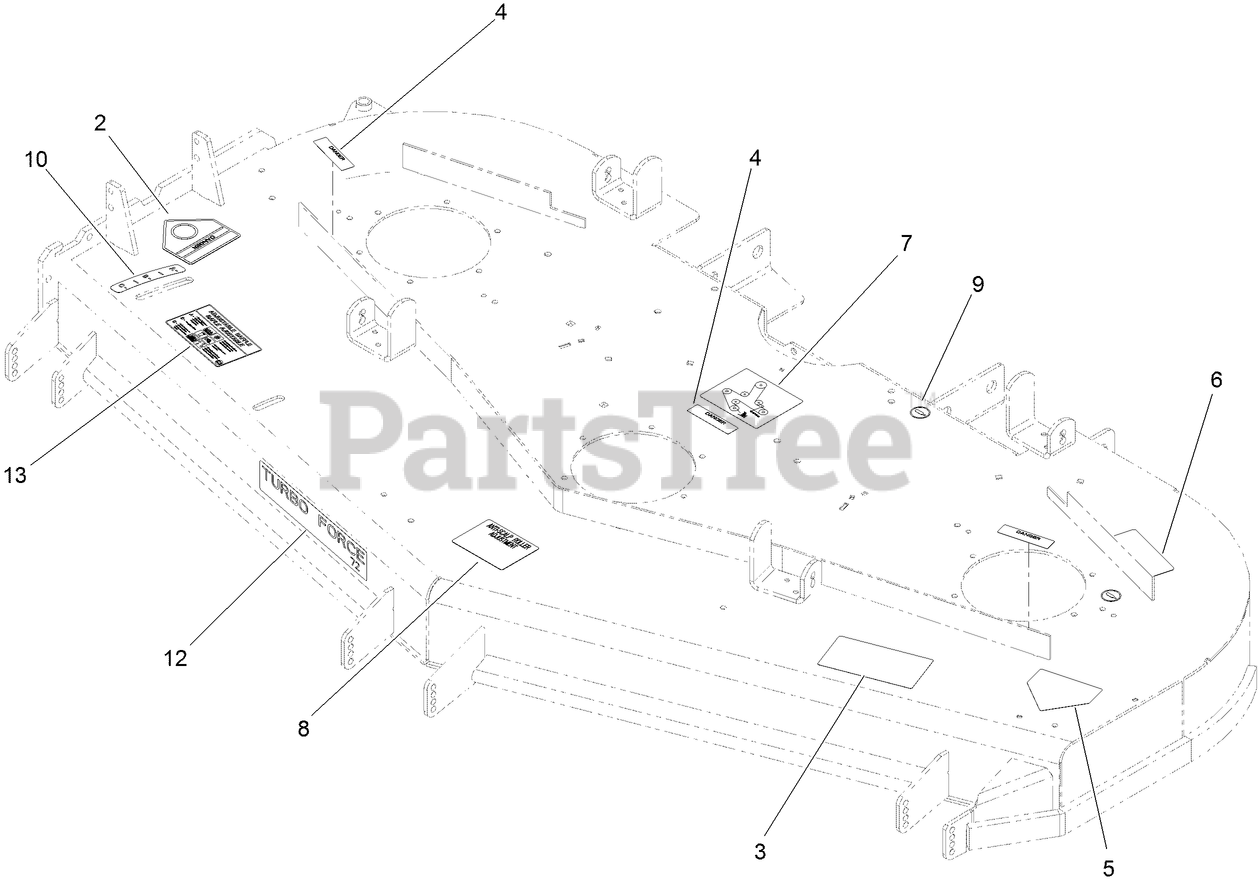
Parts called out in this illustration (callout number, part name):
2	DECAL-DANGER
3	DECAL-DANGER, THROWN OBJECT
4	DECAL-COVER, MISSING
5	DECAL-DANGER
6	DECAL-TORQUE
7	DECAL-ROUTING, BELT
8	DECAL-SCALP, ANTI
9	DECAL-GREASE
10	DECAL-SETTING, BAFFLE
13	DECAL-ADJUSTMENT, BAFFLE
